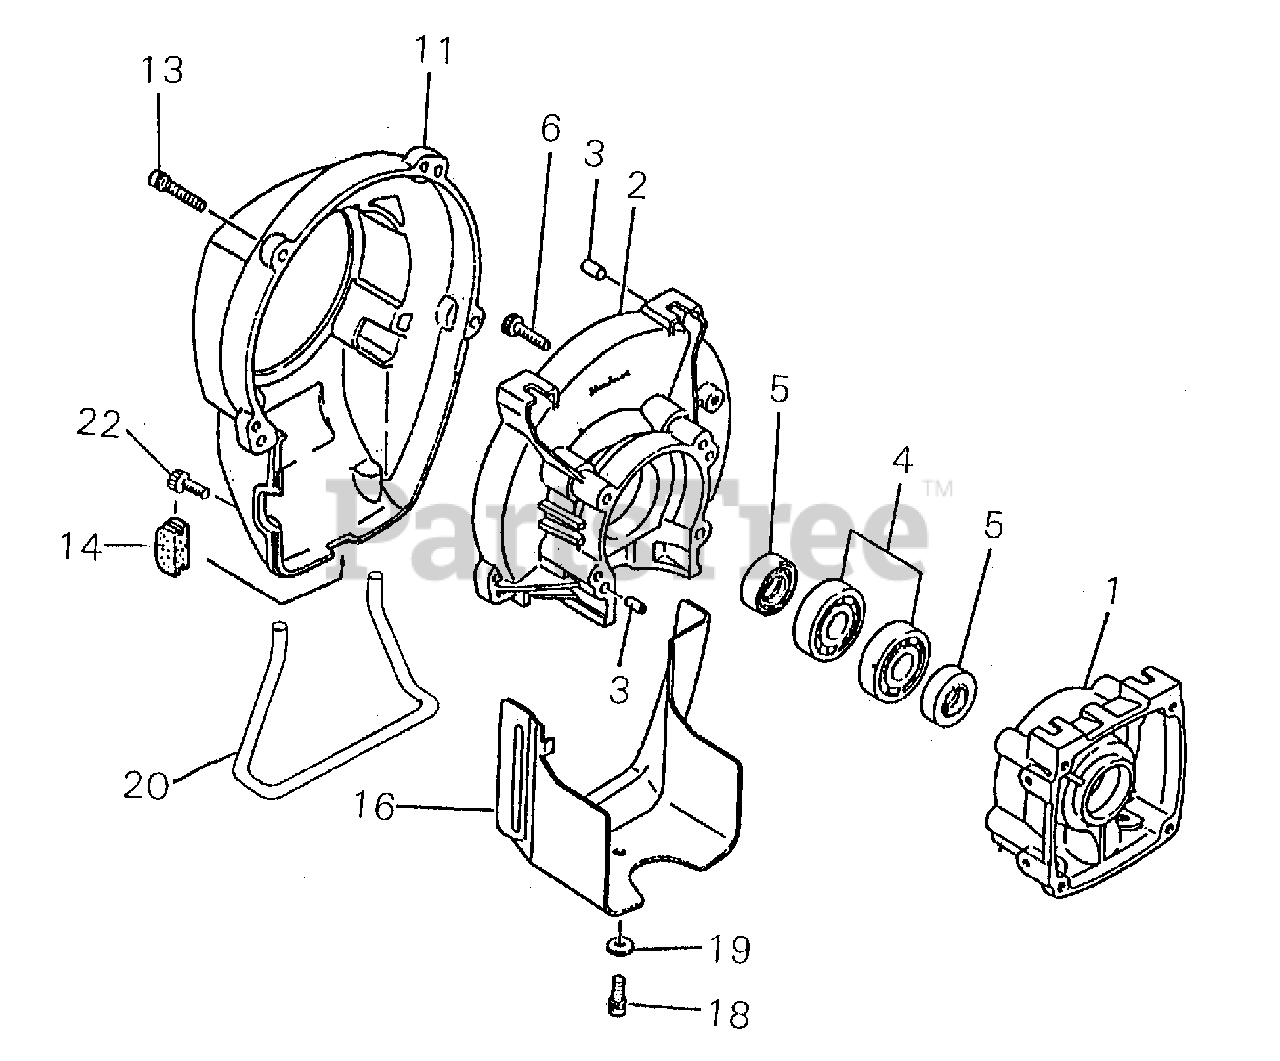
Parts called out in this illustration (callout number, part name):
1	CRANKCASE - REAR
2	CRANKCASE - FRONT
3	PIN - LOCATING
4	BEARING, BALL - 6202C3
5	SEAL, OIL
6	SCREW - 5X30
11	CASE, FAN
13	SCREW - 5X20
14	GROMMET
16	COVER, ENGINE
18	SCREW - 5X14
19	WASHER
20	STAND
22	SCREW - 5X10
